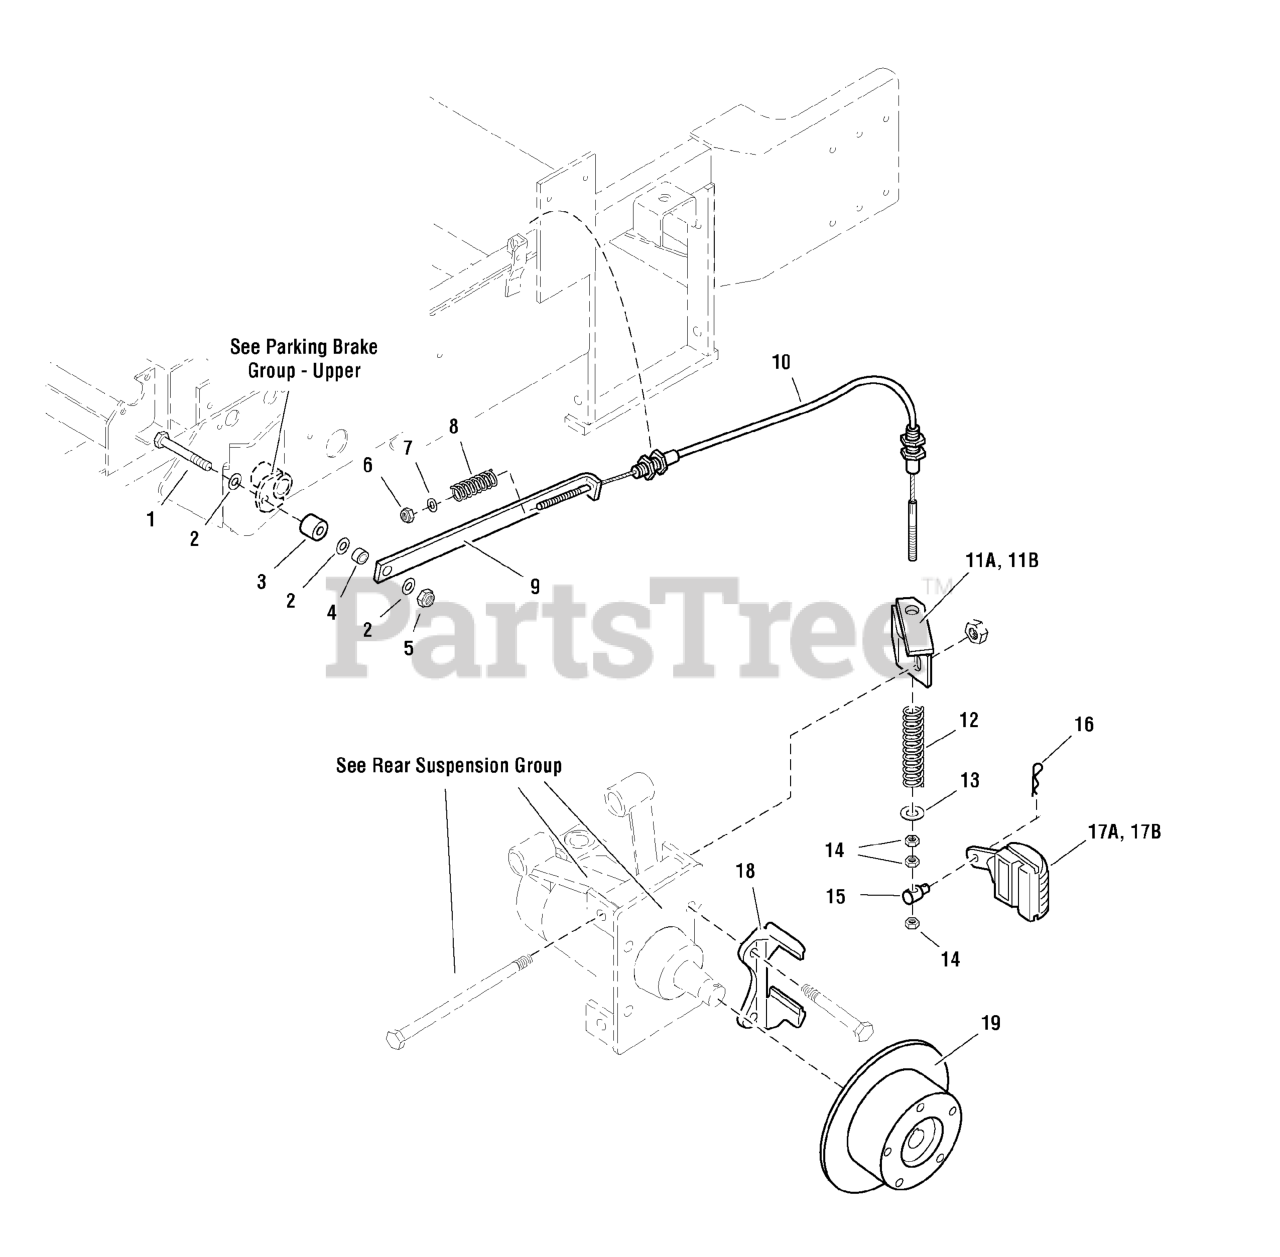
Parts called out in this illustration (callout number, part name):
1	BOLT, 3/8-16 X 2-1/4" GD5 CZ
2	WASHER, 3/8 SAE
3	SPACER, .39 x 1.00 x .88
4	SPACER, .38 x .50 x .27
5	NUT, 3/8-16 HEX NYLON LOCK
6	NUT, 5/16-24 HEX NYLON LOCK
7	WASHER, 5/16" SAE
8	SPRING, Compression
9	LINK, Brake Lock
10	CABLE, Brake
11A	BRACKET, Cable Mount-LH
12	SPRING, Compression
13	WASHER, 5/16" Fender
14	NUT, 5/16-24 Hex
15	ADJUSTER, Brake Linkage
16	HAIRPIN CLIP
17A	BRAKE CALIPER, LH
18	MOUNT, Brake Caliper
19	HUB, 8" Brake Disc
